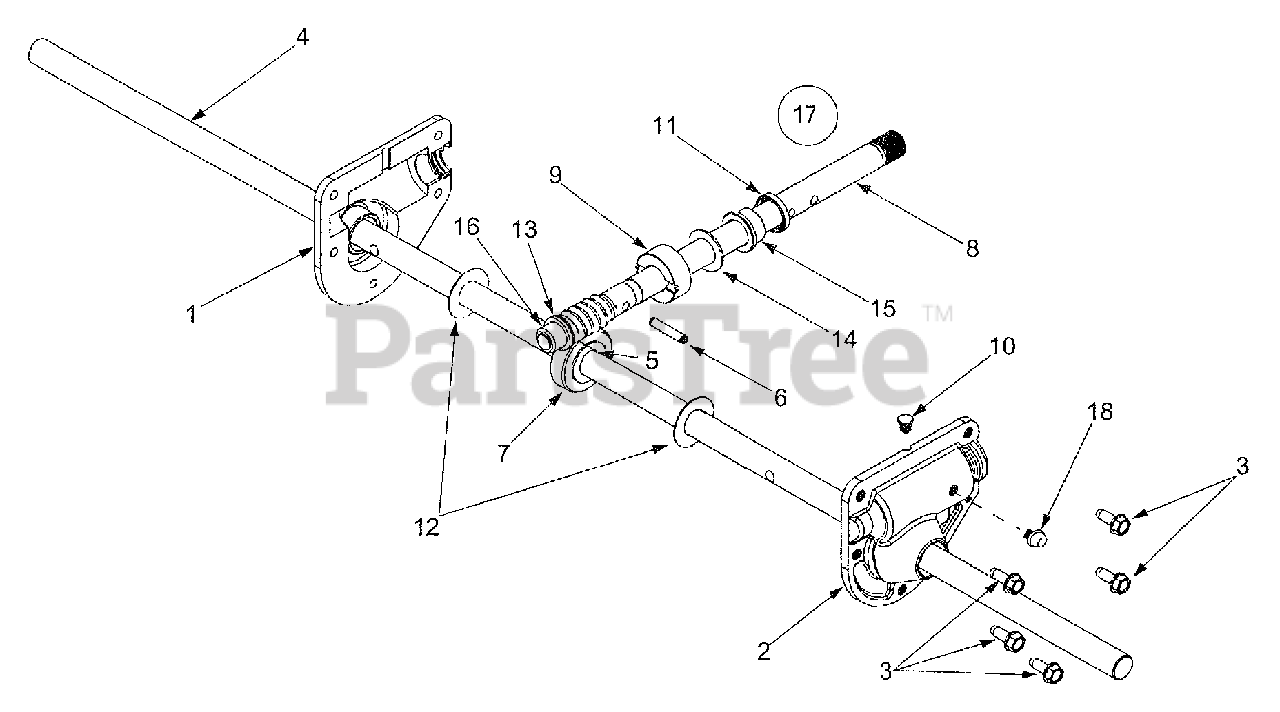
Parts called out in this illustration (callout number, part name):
1	RH Housing
2	LH Housing w/Fitting
3	Self Tapping Screw, 1/4-20 x 75
4	Spiral Axle, 26"
4	Spiral Axle, 30"
5	Hi Pro Key, 3/16 x 5/8
6	Spring Spiral Pin, 25 x 1 25
7	Worm Gear, 20-tooth
8	Worm Shaft
9	Thrust Collar
10	Grease Plug
11	Grease Seal
12	Flat Washer, .76 x 1.5 x .030
13	Flat Washer, .508 x 1.0 x .020
14	Flat Washer, .76 x 1.5 x .060
15	Flange Bearing, .75 x 1.0 x .59
16	Flange Bearing, .503 ID x .75 OD
17	Gear Ass'y Complete, 26"
17	Gear Ass'y Complete, 30"
18	Grease Fitting, 3/16" Drive
